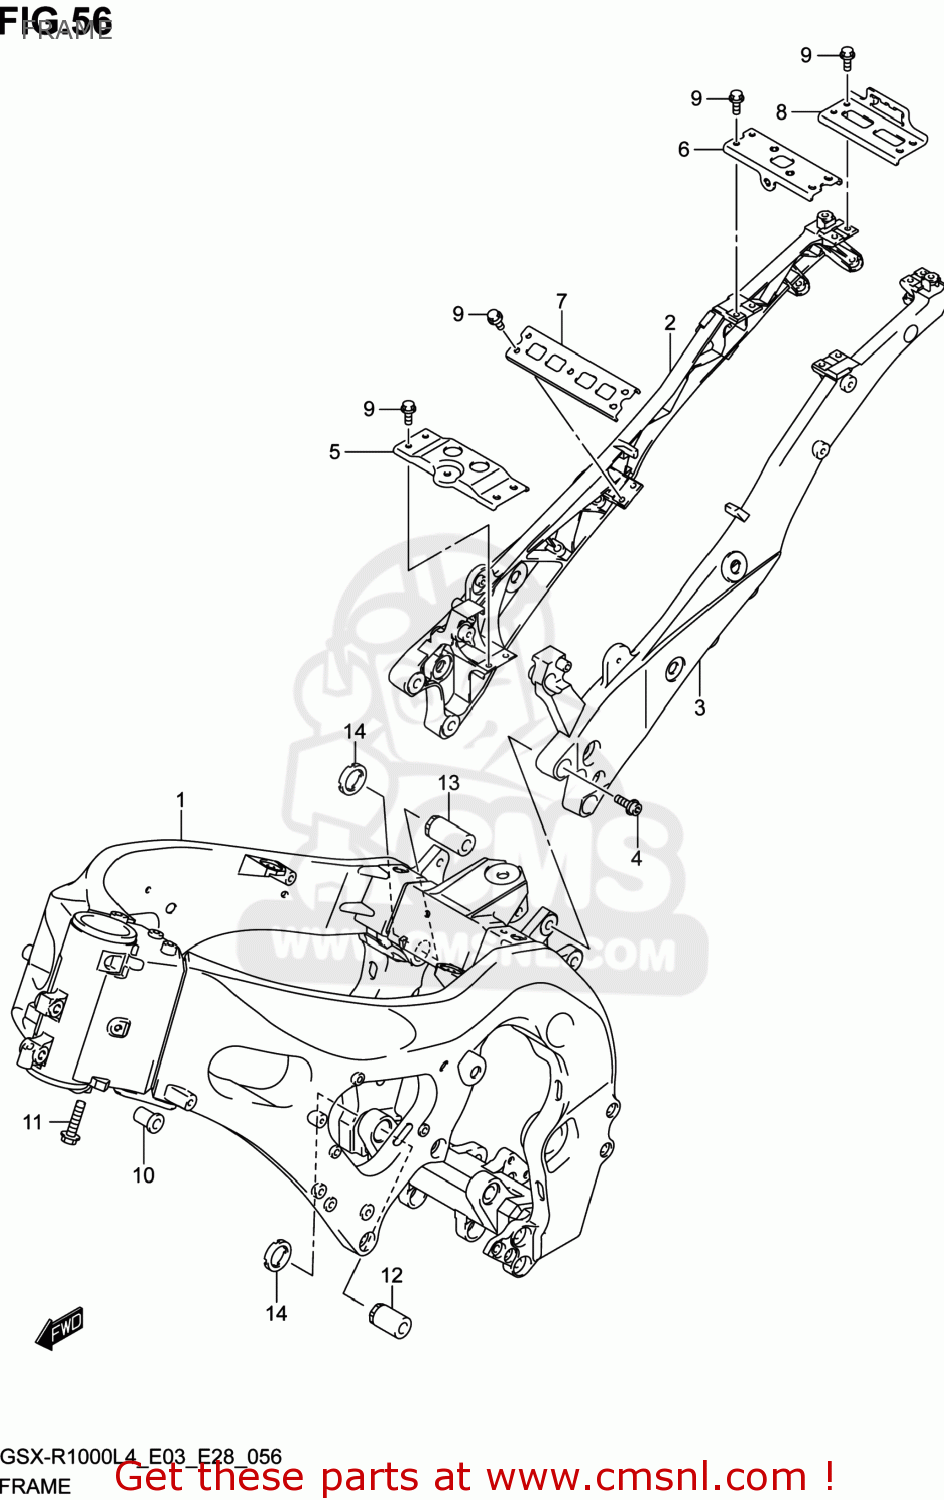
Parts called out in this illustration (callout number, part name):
1	FRAME(BLACK)
2	RAIL,SEAT,R
3	RAIL,SEAT,L
4	BOLT,SEAT RAIL
5	BRIDGE,SEAT RAIL FR
6	BRIDGE,SEAT RAIL UPR
7	BRIDGE,SEAT RAIL LWR
8	BRIDGE,SEAT RAIL RR
9	BOLT(6X12)
10	SPACER,ENGINE MOUNTING
11	BOLT(8X35)
12	BOLT,CRANK CASE ADJUST
13	BOLT,CRANK CASE ADJUST UPR
14	NUT,CRANK CASE ADJUST BOLT
